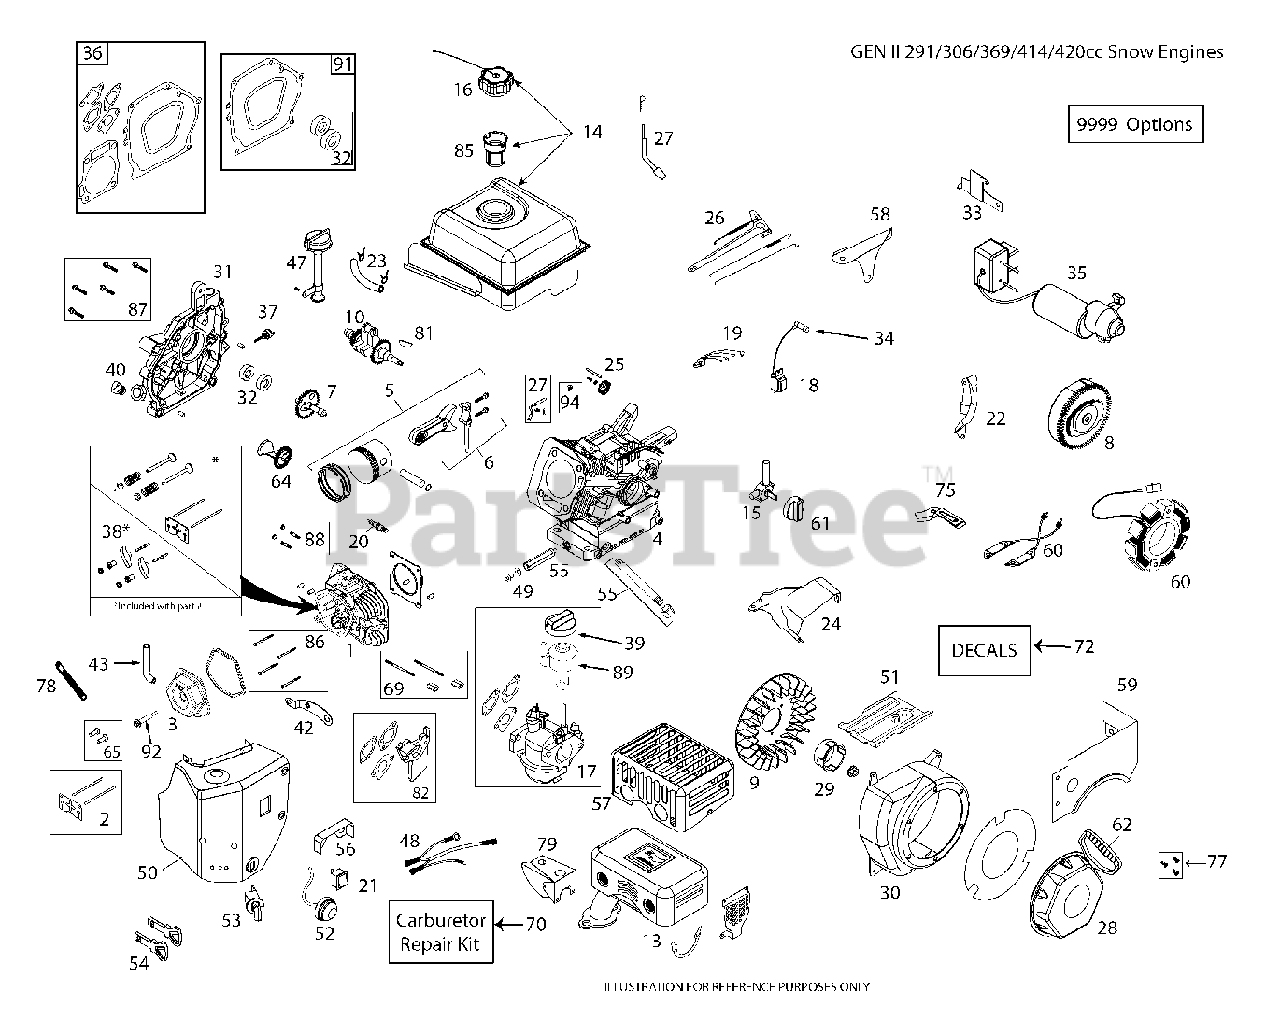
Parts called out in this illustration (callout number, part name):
1	CYLINDER.HEAD.ASSY(SK2911000)
2	PUSH ROD TAPPET KIT
3	VALVE.COVER.LCT.414CC.
4	CYLINDER ASSY SNO.LCT
5	PISTON.AND.ROD.ASSY(SK2911400)
6	CONNECTING ROD ASSY SNO.LCT
7	CAMSHAFT.LCT.291CC
8	FLYWHEEL.EL.ST.SKSNO2401.1
9	FLYWHEEL.FAN
10	CRANKSHAFT LCT.SKSN2805.1
13	MUFFLER (SKSN2210.1)
14	FUEL TANK ASSY - SNOW (291CC)
15	FUEL.PETCOCK.SNOW(SKSN4900)
16	FUEL.TANK.CAP.SNOW(SKSN4301)
17	CARBURETTOR LCT
18	COIL.IGN.CDI.SKSN2403.1
19	Husqvarna TBD
20	SPARK.PLUG(SK2911550)
21	ON/OFF.SWITCH.SNOW(SKSN4403)
22	SHIELD.U/FYWHL.CHARG(SKSN4604)
23	FUEL HOSE KIT
24	TOP.SHIELD.LCT.
25	GOVERNOR.GEAR.ASSY(SK2912900)
26	GOVERNOR.ARM.ASSY.(SKSN2502)
27	GOVERNOR.SHAFT.(SK2913100)
28	RECOIL.START.ASSY.(SKSN2600)
29	STARTER.CUP.SMALLSNOW(SKSN2601
30	BLOWER HOUSING.BLK ES LCT 291
31	CRANKCASE.COVER.ASY(SK2913600)
32	OIL.SEAL.KIT(SK2913900)
33	SWITCHBOX BRACKET ES LCT 291 S
34	SPARK.PLUG.BOOT.SNW,SKSN4691.1
35	ELECTRIC.START.ASSY(SKSN2400.2
36	ENGINE.GASKET.KIT(SK2914300)
37	DIPSTK.OIL.BLK.LCTSK4143711.1
38	ROCKER ARM KIT
39	CHOKE.KNOW.SNOW(SKSN4500)
40	NONREMVABLE.OIL.PLUG(SK4143715
42	CDI.BOX.BRKT.SNOW(SKSN4402)
43	TUBE.BREATHER.LCT.219CC/414CC
47	TUBE OIL FILL KIT.LCT SKSN4950
48	WIRE.HARNESS(SKSN4406)
49	OIL.DRAIN.PLUG
50	HEATER.BOX.ASSY.SNOW(SKSN2100)
51	SHIELD.CYLINDER.SNOW(SK4141010
52	PRIMER.BULB.ASSY(SKSN4304)
53	KEY.SWITCH.ASSY.SNOW(SKSN4401)
54	KEY SET(2 KEYS) SKSN0407.1
55	OIL PIPE DRAIN EXTENDED.LCT SK
56	SHIELD.VAPOR(SKSN4606)
57	SHIELD.MUFFLER.
58	GOVERNOR.LINK.SHIELD(SKSN2501)
59	FUEL.TANK.SKIRT(SKSN2101)
60	ALTERN.60WATT.SKSN2402.1
61	FUEL KNOB-SNOW
62	HANDLE.RECOIL.DELUXE.LCT
64	Husqvarna TBD
65	TAPPET KIT.LCT.SK2911005.1
69	STUD.CARB.MOUTING.KIT.291CC
70	CARBURETTOR REPAIR KIT 291CC/4
72	Husqvarna TBD
75	Husqvarna TBD
77	Husqvarna TBD
78	Husqvarna TBD
79	BOLT.KIT.RECOIL.LCT.ALL.ENGINE
81	KEYS.FLYWHEEL.136/291CC.5PACK
82	SPACER.CARBURETOR.291CC.LCT
85	STRAINER.FUEL.TANK.LCT.208CC
86	KIT.BOLT.CYLINDER.HEAD.(4PC)
87	KIT.BOLT.CRANKCASE.COVER.291CC
88	STUD.MUFFLER.KIT.LCT
89	KNOB LCT.SKSN5325.1 SPEED
91	GASKET KIT CRANKSHAFT.LCT
92	CENTER VALVE COVER BOLT
93	Husqvarna TBD
94	Husqvarna TBD
9999	HIGH.ALTITUDE.JET.(>6,000FT)
